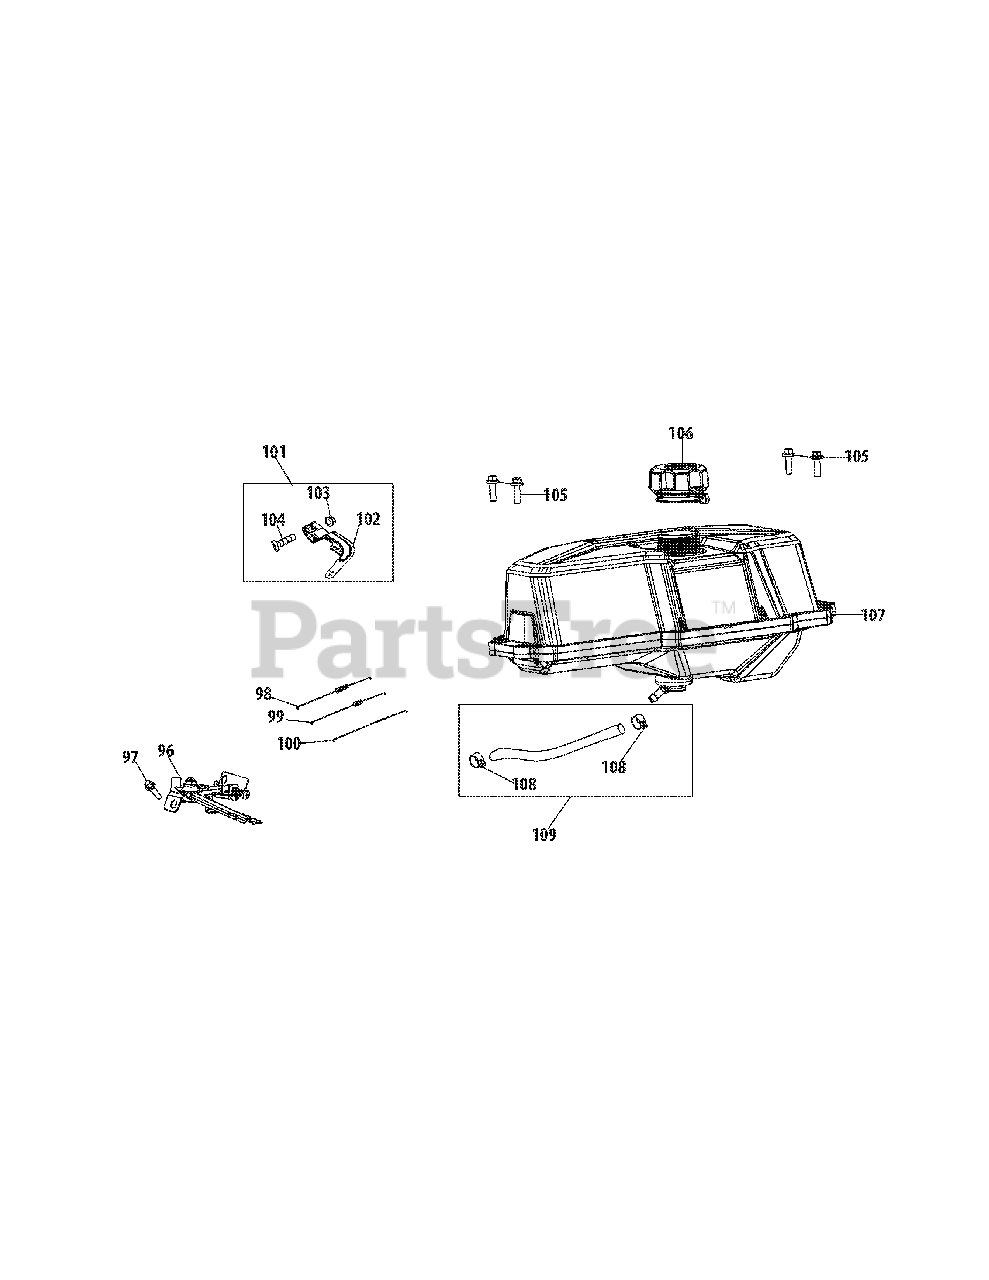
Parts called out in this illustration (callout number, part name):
96	Governor Gear Bracket Assembly
97	Bolt, M6×12
98	Governor Spring
99	Idle Spring
100	Throttle Linkage
101	Governor Lever
102	Governor Lever
103	Nut, M6
105	Bolt, M6×22
106	Fuel Cap
107	Fuel Tank
108	Clamp
109	Fuel Hose 6.3×12.5×133
